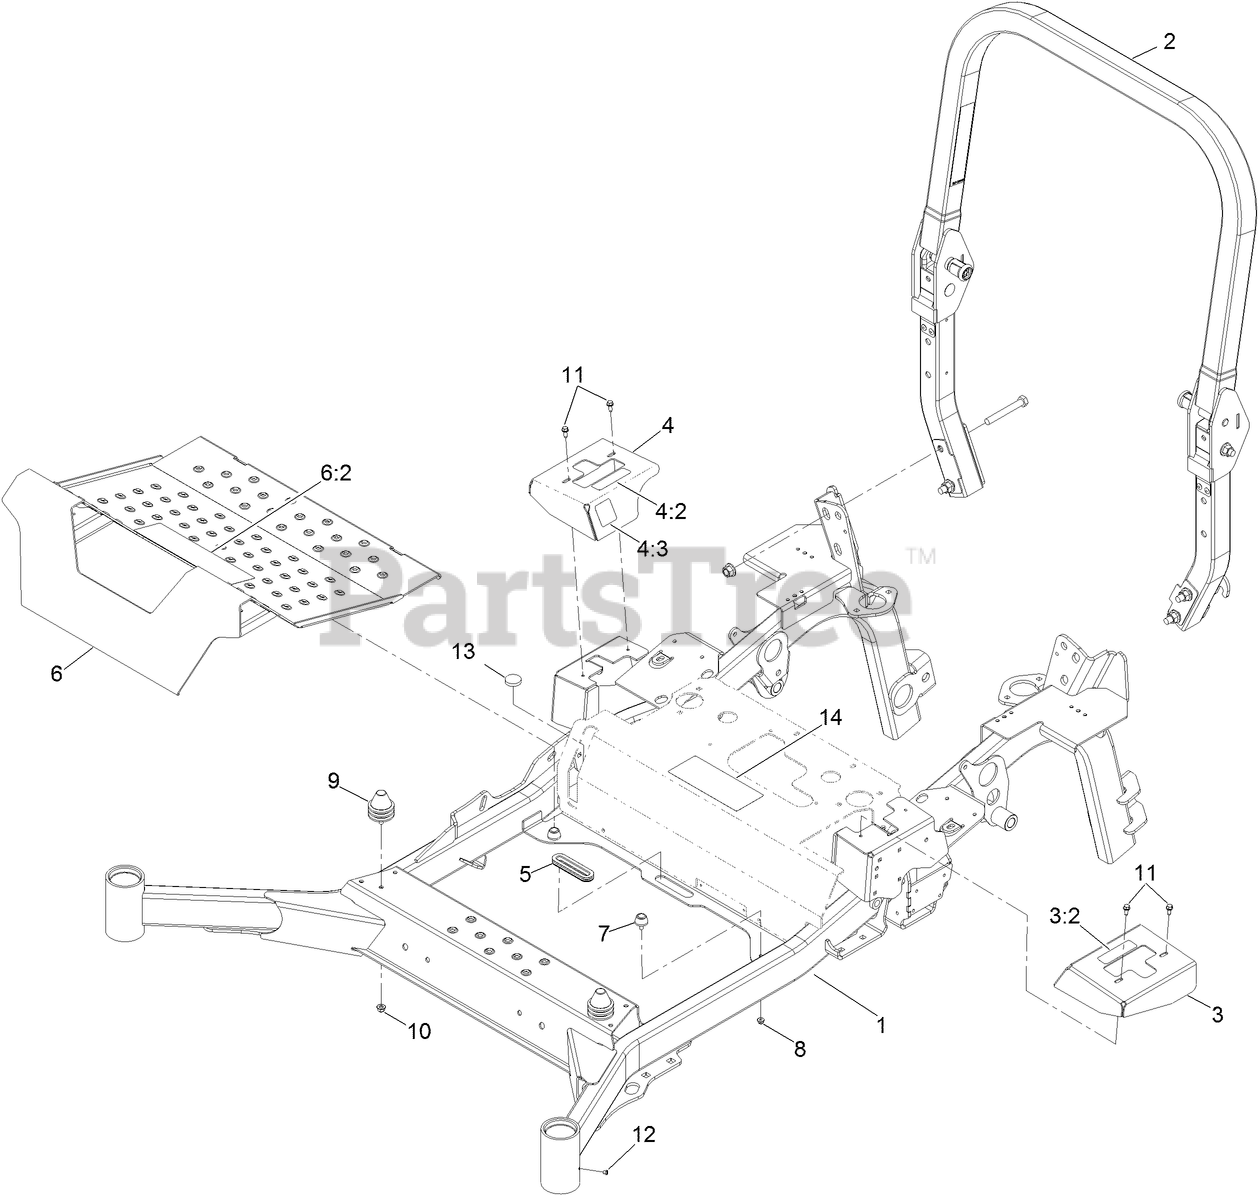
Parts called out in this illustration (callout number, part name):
1	FRAME
2	ROPS ASM
3	COVER-MOTION CONTROL, LH
3:2	DECAL-CONTROL, MOTION
4	COVER-MOTION CONTROL, RH
4:2	DECAL-CONTROL, MOTION
4:3	DECAL-PARK BRAKE, CE
5	GROMMET-RUBBER
6	PAN-FLOOR
6:2	DECAL-DANGER
7	BUMPER-RUBBER
8	NUT-HF
9	ISOLATOR
10	NUT-HF, NI
11	SCREW-HWH
13	BUMPER-PUSH-IN, RUBBER
14	DECAL-SERVICE AID
